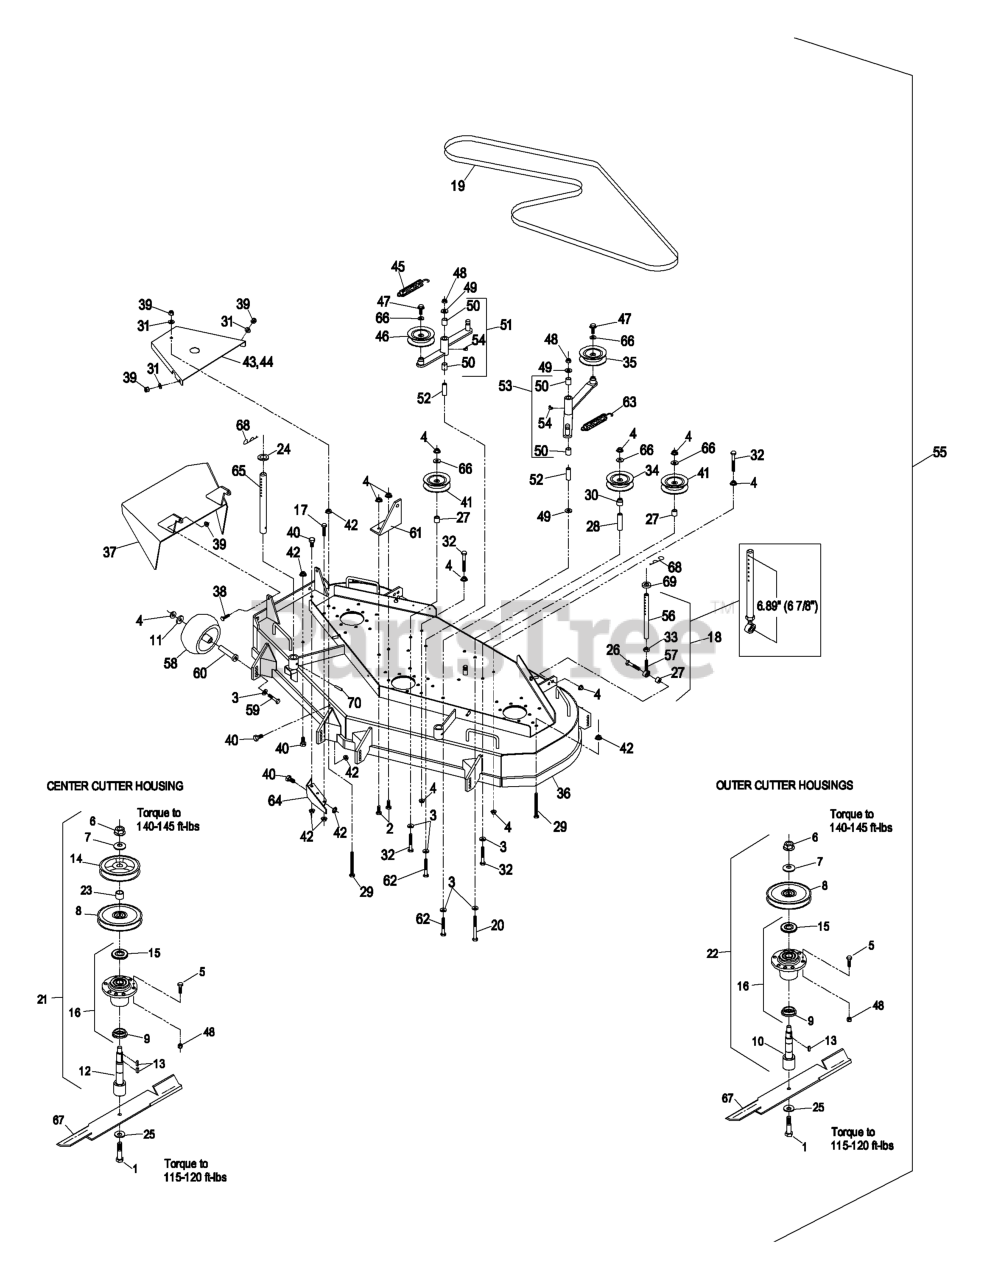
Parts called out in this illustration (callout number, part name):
1	SCREW-CAP
2	SCREW-HH
3	WASHER-BELLEVILLE
4	NUT-HHF, WHIZ
5	SCREW-HH
8	SHEAVE,BLADE DRIVE 6.30
9	SPACER-GUARD, BOTTOM
10	SPINDLE,SHORT
12	SPINDLE,LONG
14	SHEAVE,BLADE DRIVE
15	GUARD-BEARING, TOP
17	SCREW-HH
19	BELT,MULE DRIVE
20	SCREW-HH
23	SPACER,TUBE
24	SPACER-DECK SUPPORT
25	WASHER-BLADE BOLT, HEAVY
26	SCREW-HH
28	SPACER-ANCHOR, CLUTCH
29	BOLT,TAP HH
30	BUSHING,IDLER
31	WASHER-FLAT
32	BOLT-CARR
33	NUT-HEX
34	PULLEY-IDLER
35	PULLEY-IDLER
37	WLD,CHUTE FMD604
38	SCREW-HH
39	NUT-LOCK, NI
40	SCREW-HH
41	IDLER,PULLEY
43	SHIELD,BELT RH
44	SHIELD,BELT LH
45	SPRING-EXTENSION
46	IDLER,PULLEY
47	SCREW-HHF
48	NUT-LOCK, NI
49	WASHER-FLAT
50	SLEEVE-BEARING
51	ASM,IDLER ARM
52	BUSHING-PIVOT, IDLER
53	ASM,IDLER ARM
54	FITTING-GREASE, 90 DEG
55	Complete Deck Assy
56	LINK,SUPPORT
57	BALLJOINT
58	ROLLER-SCALP, ANTI
59	SCREW-HH
60	BUSHING-ROLLER
61	BRACKET,SPRING ANCHOR
62	SCREW-HH
63	SPRING-EXTENSION
64	WLD,BAFFLE DISCHARGE
65	ROD,DECK SUPPORT
66	WASHER-FLAT
68	PIN,HAIR COTTER
